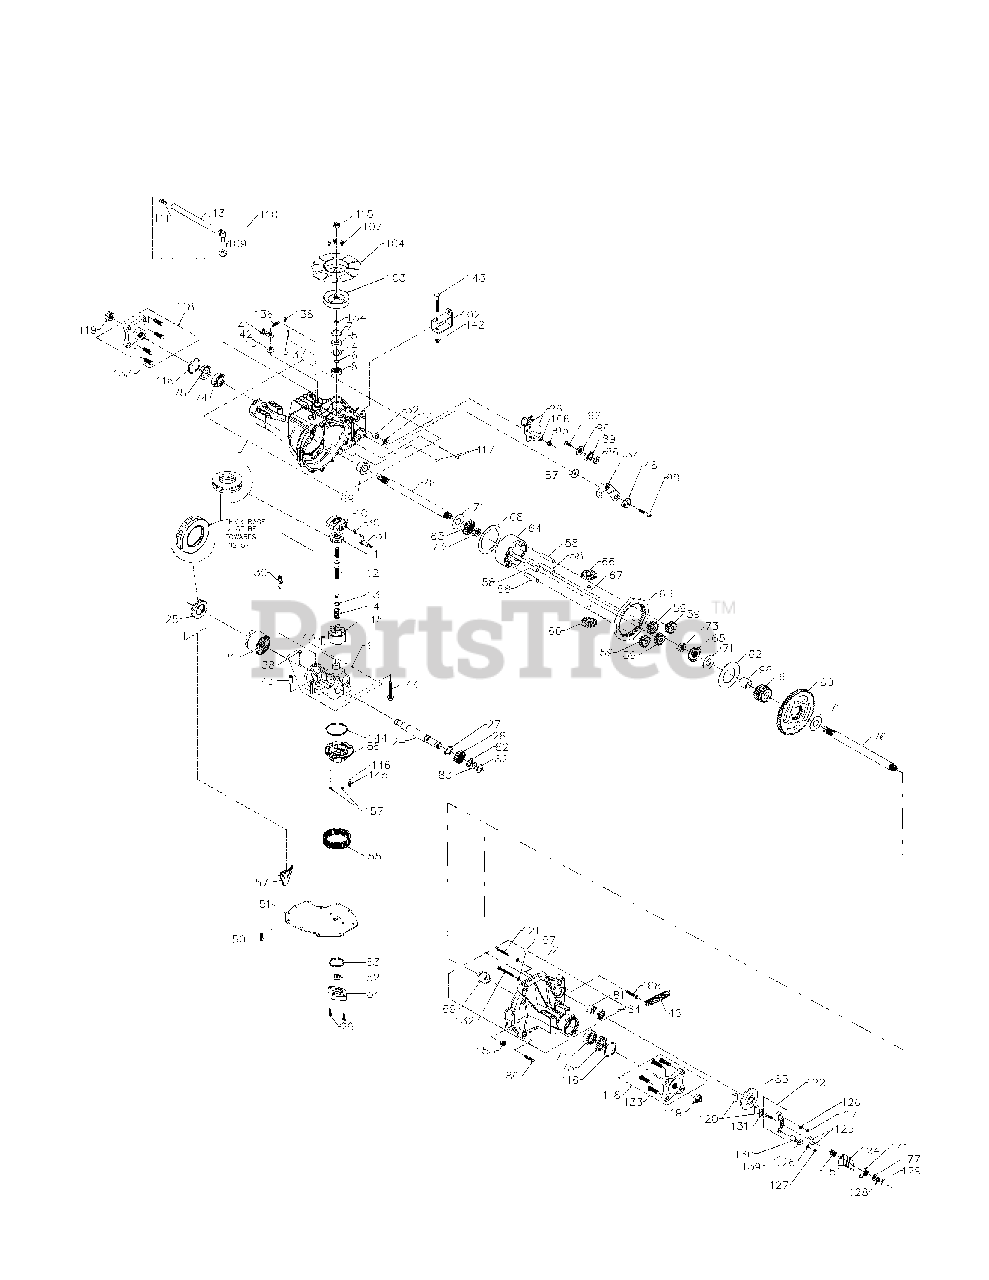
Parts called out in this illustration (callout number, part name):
1	Main Housing, Assembly
2	Housing, Assembly, RH
3	Center Section, Assembly
6	Wire Retaining Ring
7	Retaining Ring
8	Ball Bearing
10	Variable Swashplate
11	Thrust Bearing
12	Input Shaft
13	Block Thrust Washer
14	Block Spring
15	10cc Cylinder Block Assembly
21	21cc Cylinder Block Assembly
24	Output (Motor) Shaft
25	Thrust Bearing
26	Control Arm
28	16T Pinion Gear
29	Capscrew, M6 x 1-25
31	Trunnion Arm
32	Trunnion Bushing
34	Return Arm
38	Kit, Bypass Plate
39	Bypass Actuator
41	Bypass Arm
42	Retaining Ring
46	Return Spring
48	Adjusting Puck
50	Screw, 1/4-20 x .75
51	Lower Cover
52	Gerotor Assembly
54	Gerotor Cover
55	Kit, Filter
56	Charge Manifold
57	Retainer, Motor Bearing
58	Pin, Carrier
59	15T Planet Gear
60	67T Spur Gear
61	21T Sun Gear
62	Planet Thrust Plate
63	51T Ring Gear
64	Planetary Carrier
65	Miter Gear, Diff. (Splined)
66	Miter Gear, Diff.
67	Shaft, Differential
68	Differential Thrust Plate
69	Flange Bearing
71	Washer, 1.0 x 2.25 x .04
73	Hex Jam Nut, 5/8-18
74	Ball Bearing
75	Seal, 1" ID x 2.0472 x .375
76	Shaft, Axle
77	Washer
80	Torx Head Screw, 5/16-18
81	Needle Bearing
83	Retaining Ring
85	Brake Disk
86	Washer, .5 x 1.0 x .03
88	Screw, 5/16-24 x 1-1/2
89	Ball Bearing .62 ID x 1.38 x .44
90	Spacer, Locating
92	Countersunk Screw
95	Hex Lock Nut, 5/16-24
96	Sleeve Bearing
102	Torque Bracket
103	Pulley
106	Spacer, Trunnion
109	Bushing, Rubber
110	Fitting Kit
111	Cap, Vent Assembly
113	Hose/Fitting Assembly
115	Hex Nut, 1/2-20
116	Retaining Ring
117	Std. Hdls. Pin
118	Hub Assembly
119	Nut, Hex, 3/4-16
120	Puck, Brake
121	Rib Neck Bolt, 2"
122	Yoke, Brake Assembly
124	Arm, Brake
125	Pin, Brake
126	Lockwasher, 1/4 (purchase locally)
127	Nut, 1/4-20 (purchase locally)
128	Nut, Castle
129	Cotter Pin
131	Puck Plate
132	Rib Neck Bolt, 3"
133	Wheel Stud, 7/16-14
136	Extension Spring
137	Spring Pin
139	Washer, 7/8 x .265 x .125
141	Spring, Brake Arm Bias
142	Hex Lock Nut, 5/16-18 (purchase locally)
143	Bolt, 5/16-18 x 2.5 (purchase locally)
145	Spring, Relief
151	Comp. Spring, Brake Anti-Drag
154	Wire Retaining Ring
168	Shouldered Torx Hd. Screw, 5/16-18
